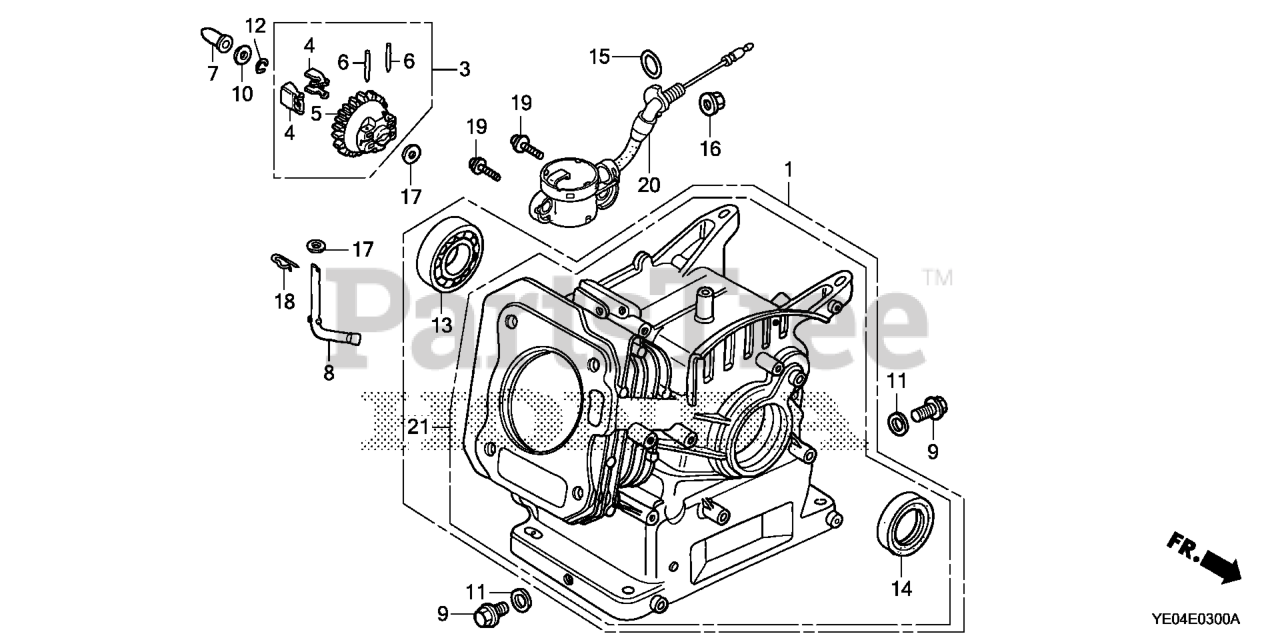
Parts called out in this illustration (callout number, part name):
1	CYLINDER ASSY. (OIL ALERT)
3	GOVERNOR ASSY.
4	WEIGHT, GOVERNOR
5	HOLDER, GOVERNOR WEIGHT
6	PIN, GOVERNOR WEIGHT
7	SLIDER, GOVERNOR
8	SHAFT, GOVERNOR ARM
9	BOLT, DRAIN PLUG
11	WASHER, DRAIN PLUG (10.2MM)
12	CLIP, GOVERNOR HOLDER
13	BEARING, RADIAL BALL (6205)
13	BEARING, RADIAL BALL (6205) (NSK)
14	OIL SEAL (25X41X6)
14	OIL SEAL (25X41X6) (ARAI) (NOT AVAILABLE)
15	O-RING (14MM) (ARAI) Use up to Engine SN 2949254.
15	O-RING (14MM) (NOK)
16	NUT, FLANGE (10MM)
17	WASHER, PLAIN (6MM)
18	PIN, LOCK (8MM)
19	BOLT, FLANGE (6X12) Use up to Engine SN 1543277.
20	SWITCH ASSY., OIL LEVEL
